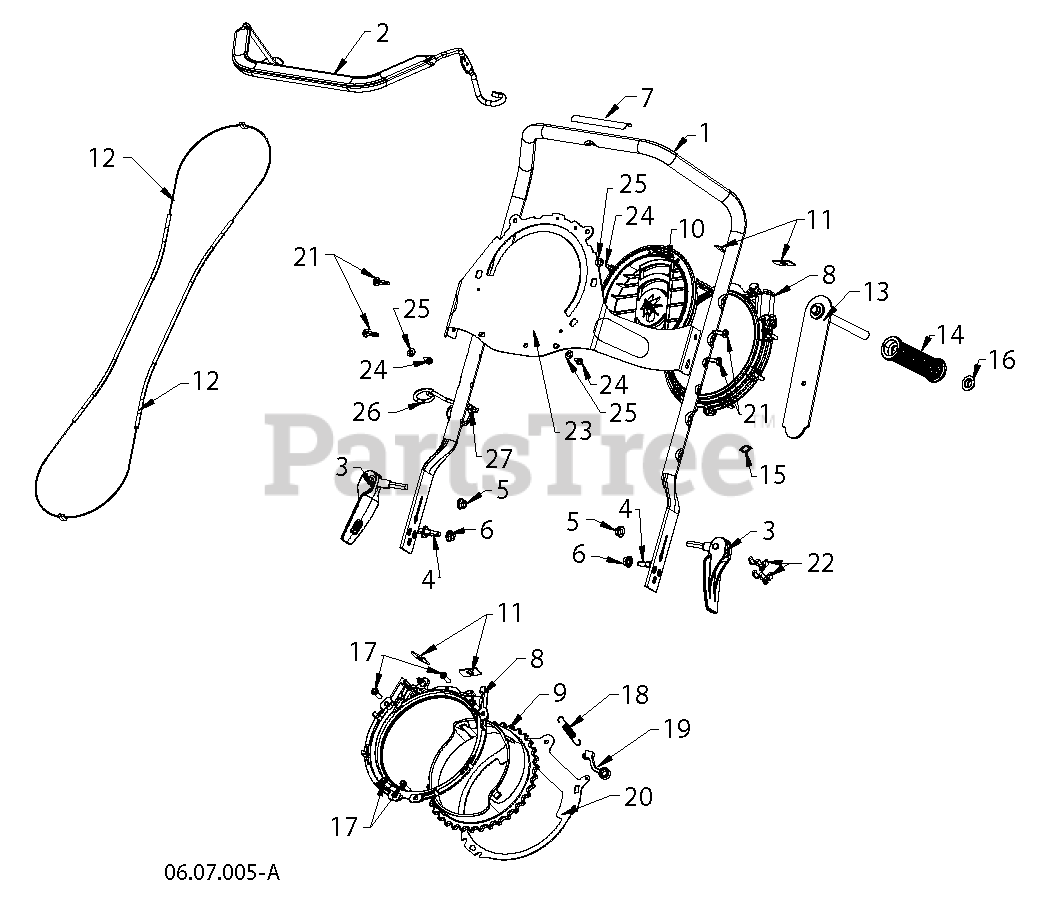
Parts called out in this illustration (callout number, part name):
1	HANDLE.UPPER.ERGO.SSST.GREY
2	BAIL.OVERMOLD.HUSQ.SSST.BLACK
3	SUBASM.QUICK.ADJUST.COLD
4	STUD.QUICK.ADJUST
5	NUT 5/16- 18 FLANGE NYLOCK.BLK
6	LOCKNUT-FLANGE 5/16-18
7	DECAL.SSST.AUGER.INSTRUCTIONS
8	CHUTE RING.RETAINER
9	CHUTE BASE.DCC.BLACK
10	PULLEY.DCC.RING.BLACK
11	CABLE.BRACKET.DCC
13	HANDLE.SUBASM.PIVOT
14	GRIP.HANDLE.SUBASM.
15	WASHER.THREE.WAVE.SPRING.SSST
16	NUT.PUSH.AXLE.0.5IN
17	SCREW.HX.13X.750
18	SPRING.CNTRL.CHUTE.ROTATE.SS/S
19	ARM.CHUTE.RATCHET
20	PLATE.CHUTE.BASE.SS.SNOW.BLACK
21	SCREW.PAN.HD.TORX.1/4-20X.750
23	BRACKET.SUPRT.DDC.STAMP.SS.SNO
24	SCREW, HEX HEAD, TAPPING
25	LOCKWASHER
26	GUIDE.ROPE.SNOW
27	NUT
